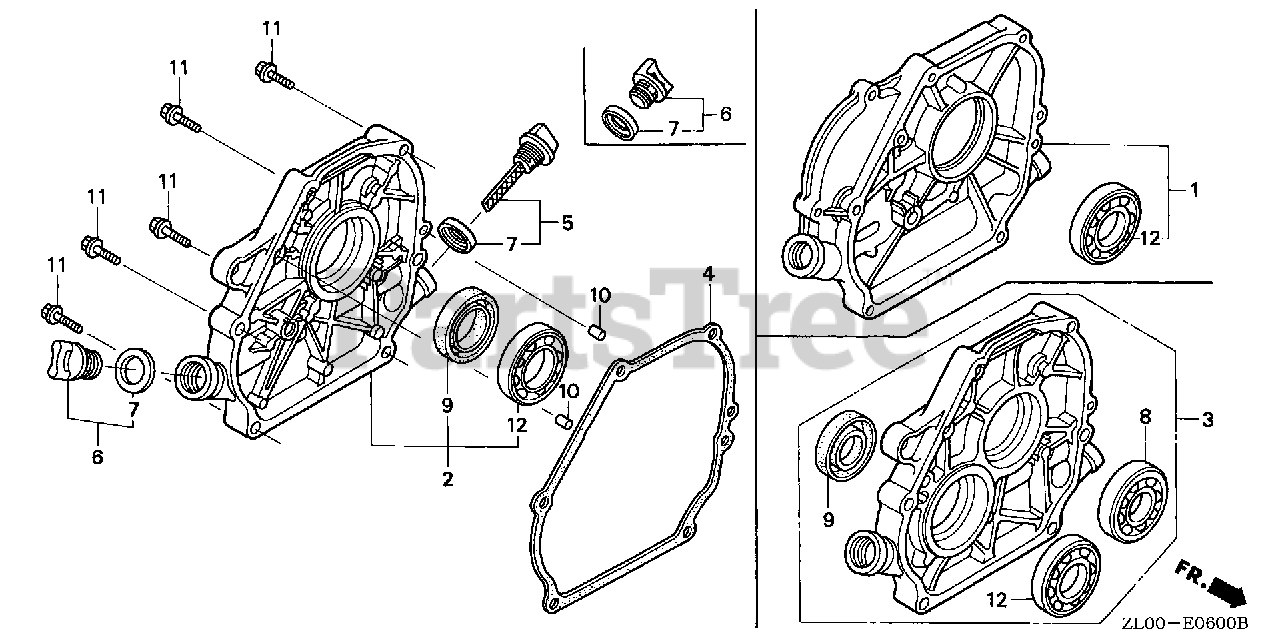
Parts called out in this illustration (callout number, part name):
2	COVER ASSY., CRANKCASE
4	GASKET, CASE COVER (NON-ASBESTOS)
4	GASKET, CASE COVER
5	CAP ASSY., OIL FILLER (GRAY)
6	CAP ASSY., OIL FILLER
7	GASKET, OIL FILLER CAP
9	OIL SEAL (25X41X6)
10	PIN, DOWEL (8X14)
11	BOLT, FLANGE (8X32)
12	BEARING, RADIAL BALL (6205)
